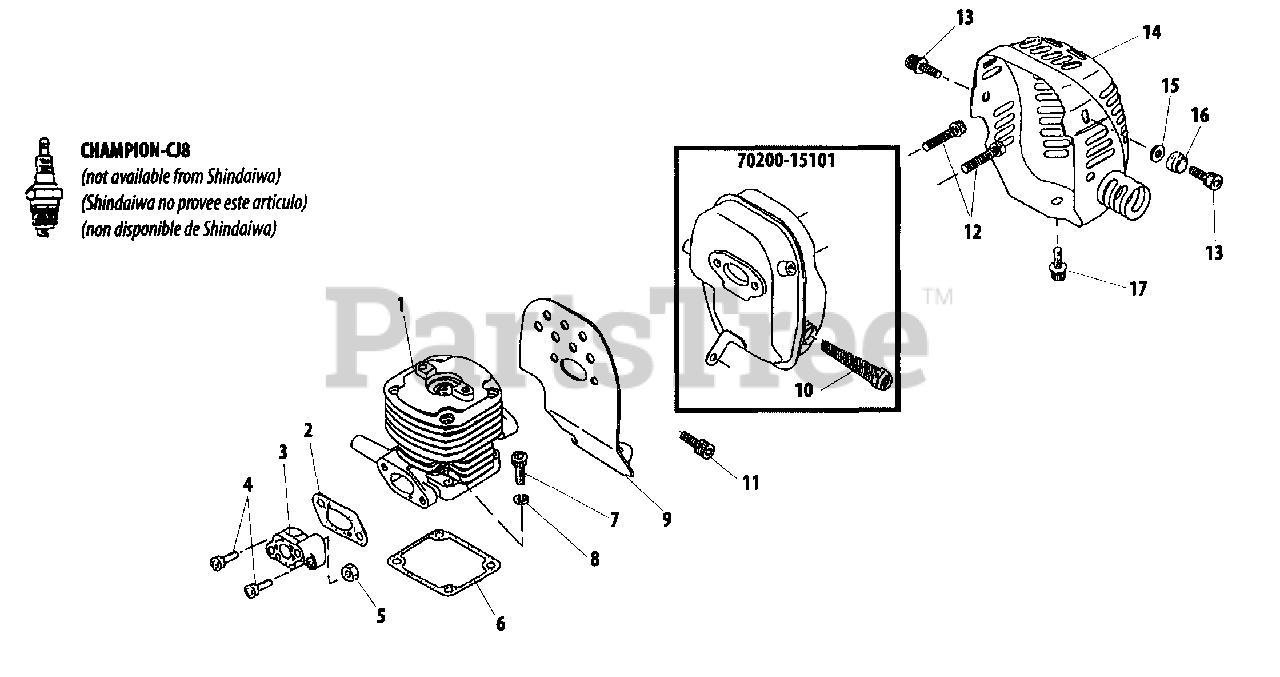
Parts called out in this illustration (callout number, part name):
1	CYLINDER
2	GASKET, INTAKE
3	INSULATOR
4	SCREW - 5X25
5	NUT
6	GASKET, CYLINDER
7	SCREW - 5X25
8	LOCKWASHER - 5
9	GASKET, EXHAUST
10	SCREEN, SPARK ARRESTOR
11	SCREW - 5X12
12	SCREW - 6X25
13	SCREW - 5X10
14	COVER, MUFFLER
15	WASHER
16	COVER
17	SCREW - 5X10
70200-15101	MUFFLER ASSY
